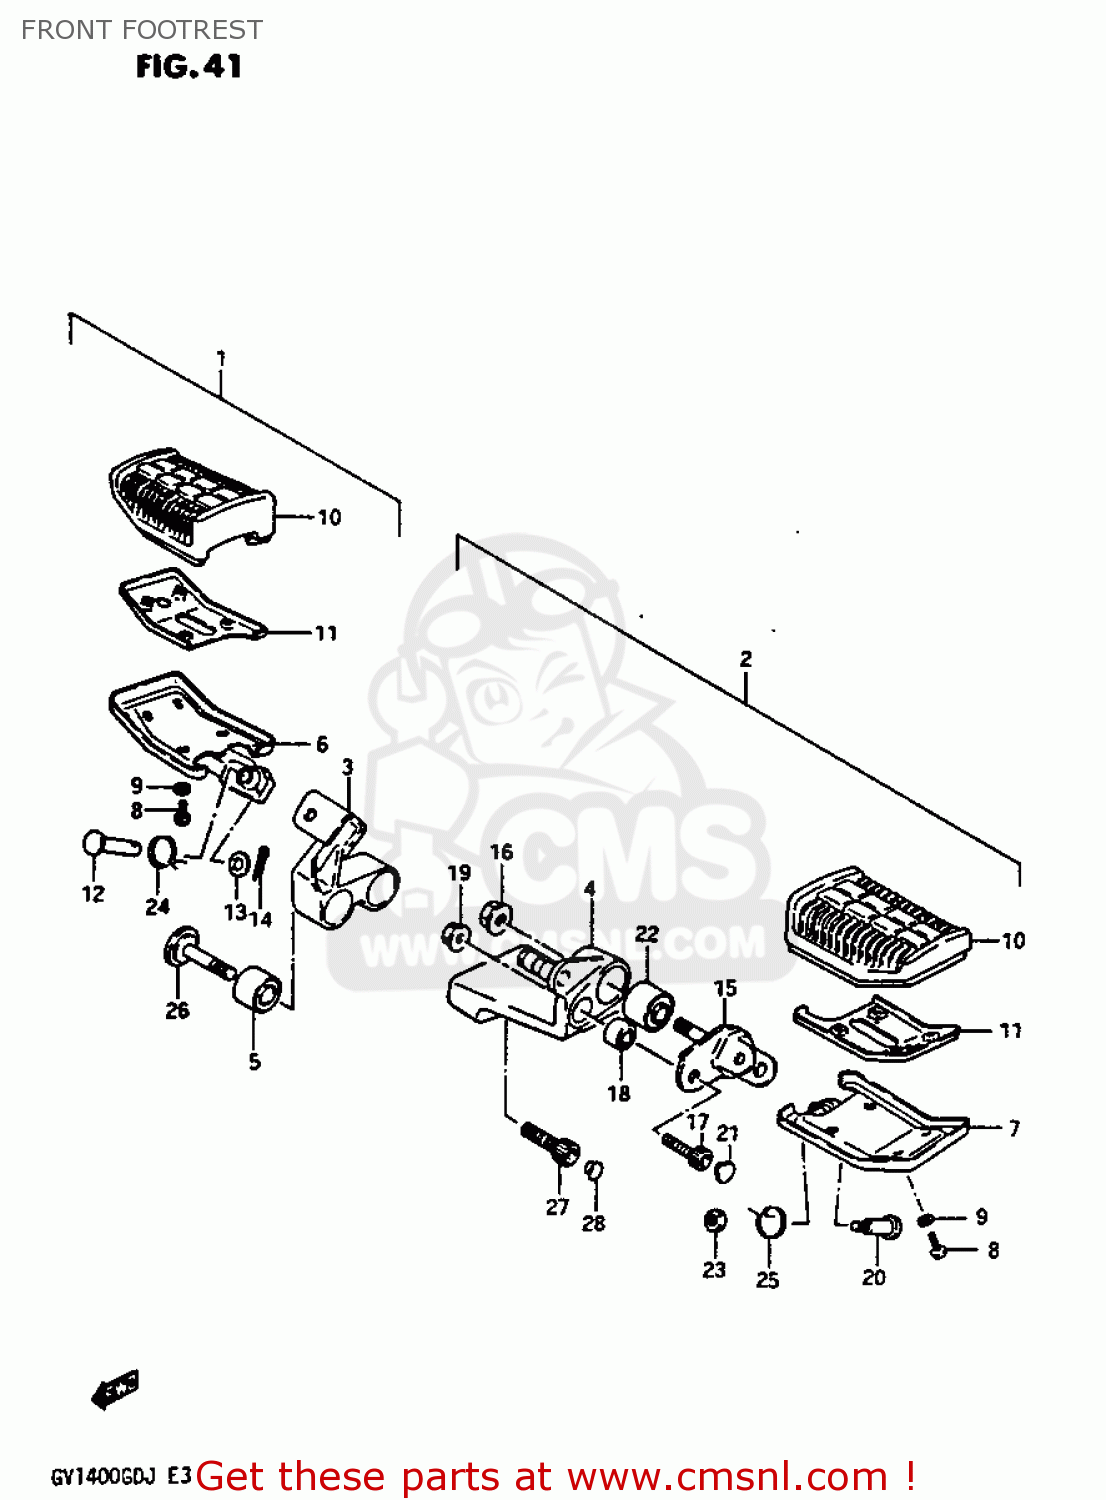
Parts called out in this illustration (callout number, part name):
1	FOOTREST ASSEMBLY,FRONT,RIGHT
2	FOOTREST ASSEMBLY,FRONT,LEFT
3	BAR COMP,FRONT FOOTREST
4	BAR COMP,FRONT FOOTREST
5	BUSHING
6	HOLDER COMP,FRONT FOOT
7	HOLDER COMP,FRONT FOOT
8	SCREW
9	LOCK WASHER
10	RUBBER,FR FOOTREST
11	PLATE,FOOTREST RUBBER
12	PIN
13	WASHER
14	PIN 20X20
15	BOSS COMP,FOOTREST HOLDER
16	NUT
17	BOLT, LH
18	BUSH
19	NUT
20	BOLT
21	CAP(OD:14.5)
22	BUSHING
23	NUT 6MM
24	SPRING
25	SPRING
26	BOLT 10X51
27	BOLT, LH
28	CAP
